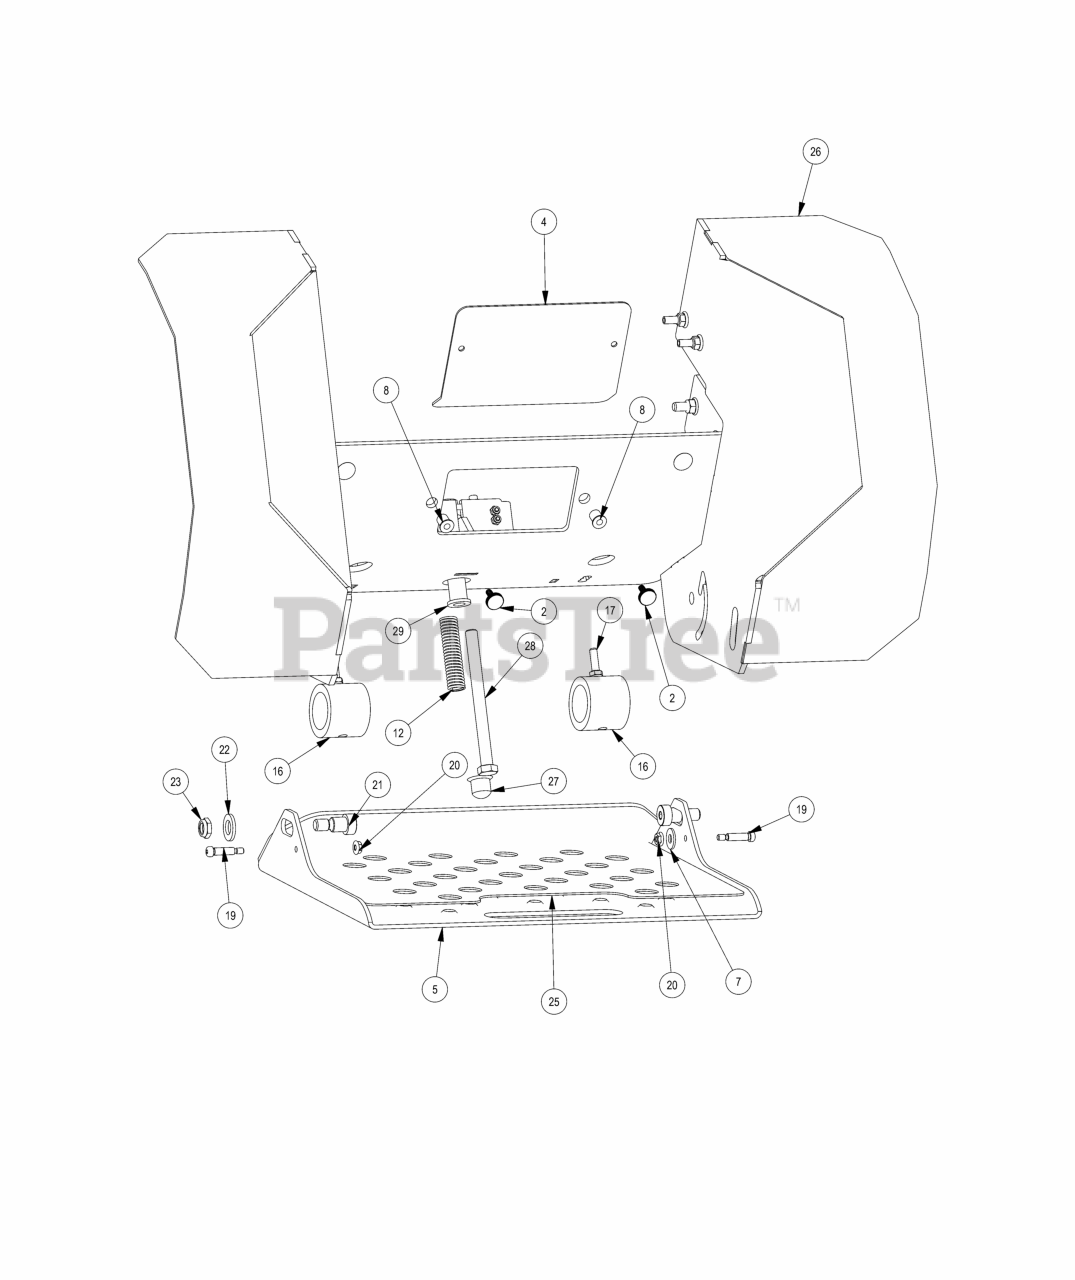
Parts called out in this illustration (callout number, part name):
1	MZ Deck Idler Spacer
2	1/4"-20 x 3/4" Knurled Thumb Screw
3	safety Switch
4	2019 Stand On Access Panel Plate Black Part
5	2020 36" Revolt Platform Plate-Powdercoated
6	10-24 NYLON INSERT LOCKNUT ZINC
7	5/16 USS FLAT WASHER (7/8 OD) ZINC
8	3326 Wellnut (1/4-20 x 5/18")
9	3/8" Nylock Flange Nut
10	3/8-16 X 1-1/4 CARRIAGE BOLT ZINC
11	10-24 X 3/4 BUTTON SOCKET CAP SCREW 18-8 STAINLESS STEEL
12	Rider Presence Spring 9657K145
13	1/2-13 HEX SERRATED FLANGE NUT HARD/ZINC
14	5/16" Nylock Flange Nut Zinc
15	5/16-18 X 1-1/4 CARRIAGE BOLT ZINC
16	2019 Revolt Platform Dampener
17	5/16-18 X 1 HEX CAP SCREW (GR.5) ZINC
18	5/16" Flange Nut
19	Steel Shoulder Screw 1/4"-20 x 7/8" Diameter 5/16"
20	1/4-20 HEX SERRATED FLANGE NUT HARD/ZINC
21	5/8'' x 5/8'' Shoulder Bolt
22	.630 ID Plastic Washer
23	1/2" Nylcock Nut (1/2 Jam)
24	3/8-16 X 1-1/4 HEX CAP SCREW (GR.5) ZINC
25	Grip Tape for 026-0158-00
26	2023 36 Platform Support
27	Hex Nut Cap
28	1/2-13 X 6 HEX CAP SCREW (GR.5) ZINC
29	.504 ID X .740 OD X 1.625 LGTH SLEEVE WASHER NYLON
